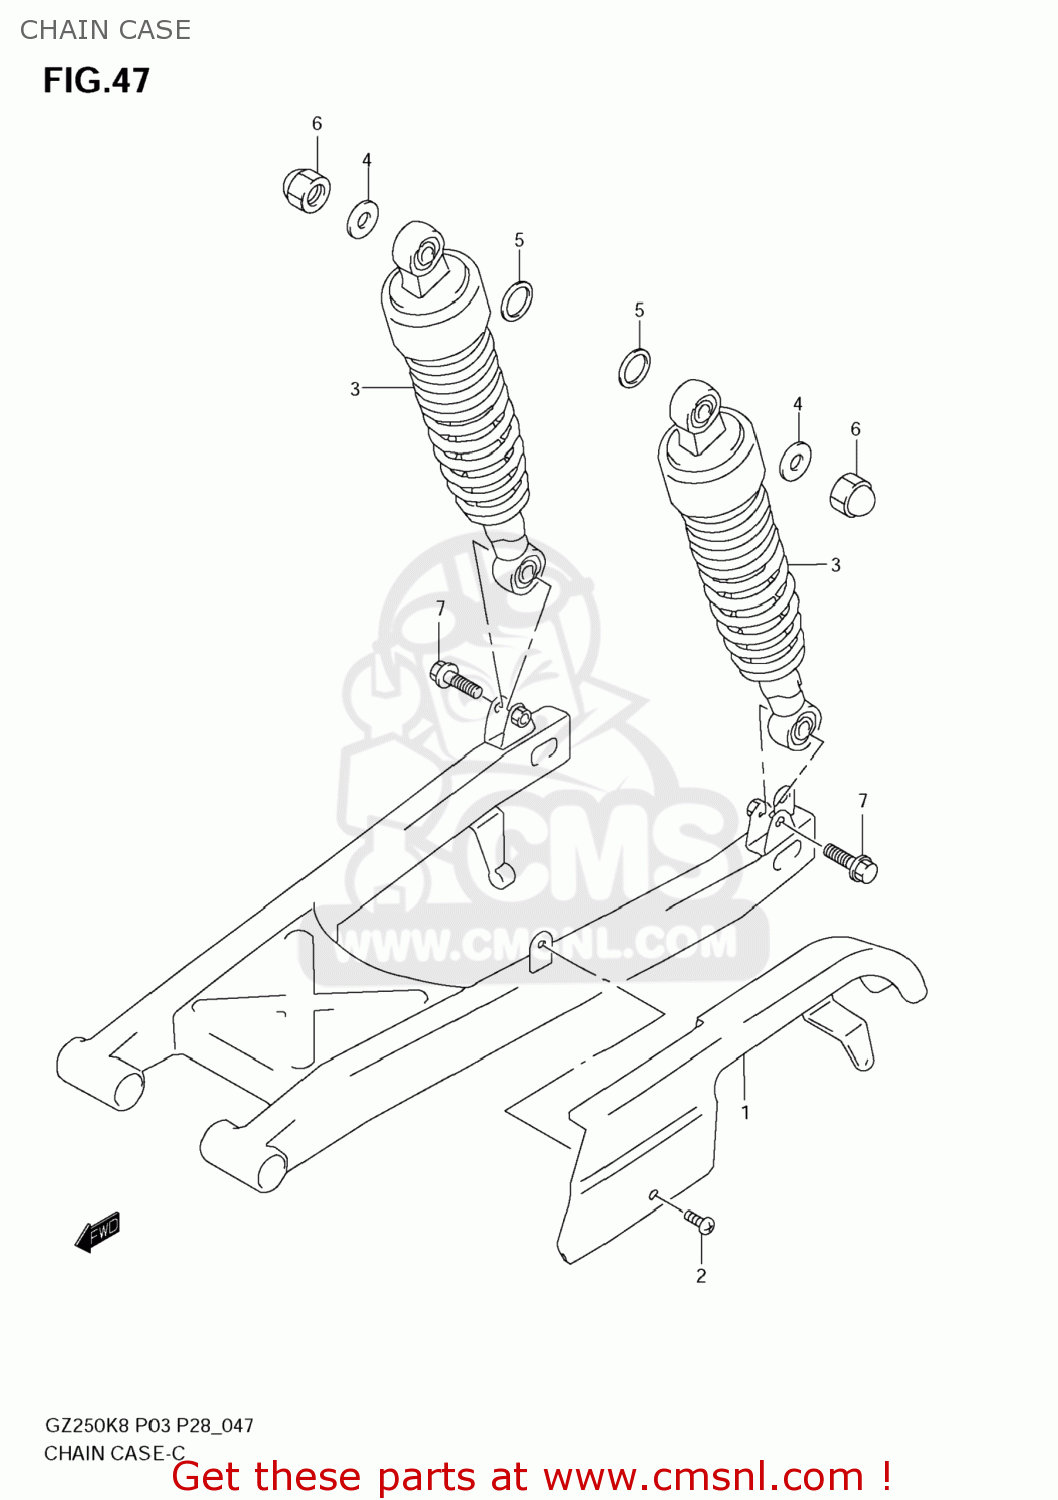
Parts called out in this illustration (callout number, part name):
1	CASE,CHAIN GZ1
2	SCREW
3	ABSORBER ASSY,RR SHOCK
4	WASHER (10.5X24X2.3)
5	WASHER
6	NUT
7	BOLT(10X37)
